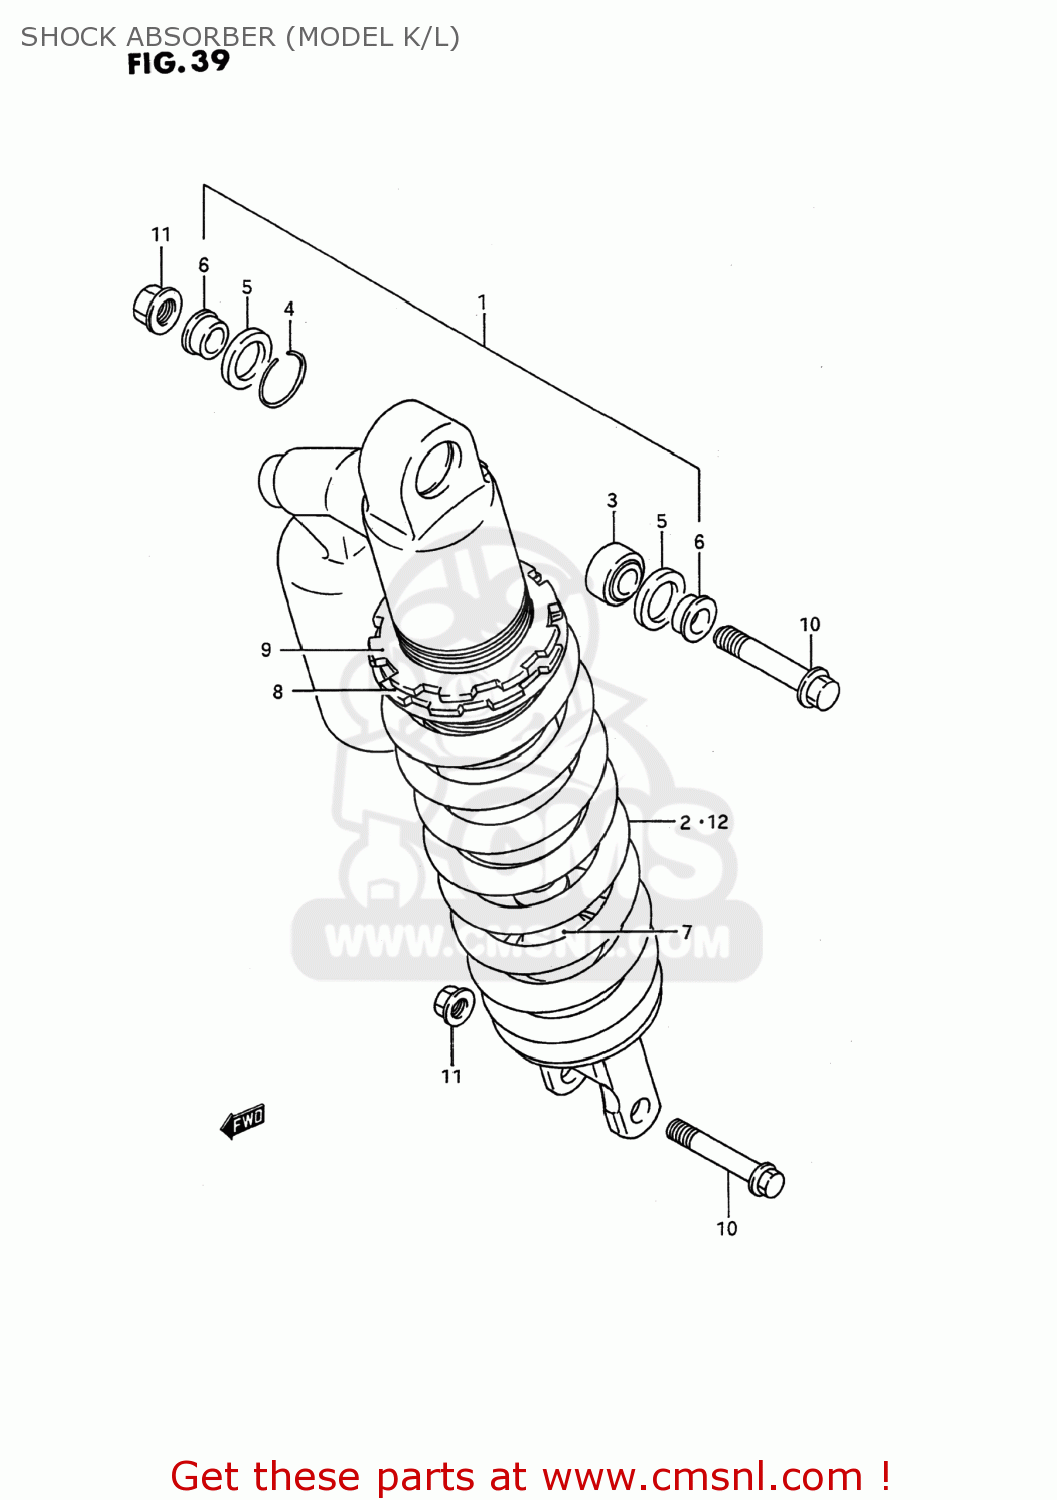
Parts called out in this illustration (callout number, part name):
1	ABSORBER ASSEMBLY,REAR SHOCK
2	SPRING
3	BEARING,RR CUSHION LEVER
4	RING
5	DUST SEAL
6	COLLAR
7	ROD,PISTON
8	GUIDE,SPRING
9	NUT
10	BOLT,REAR SHOCK ABSORBER
11	NUT
12	SPRING (HARD)
